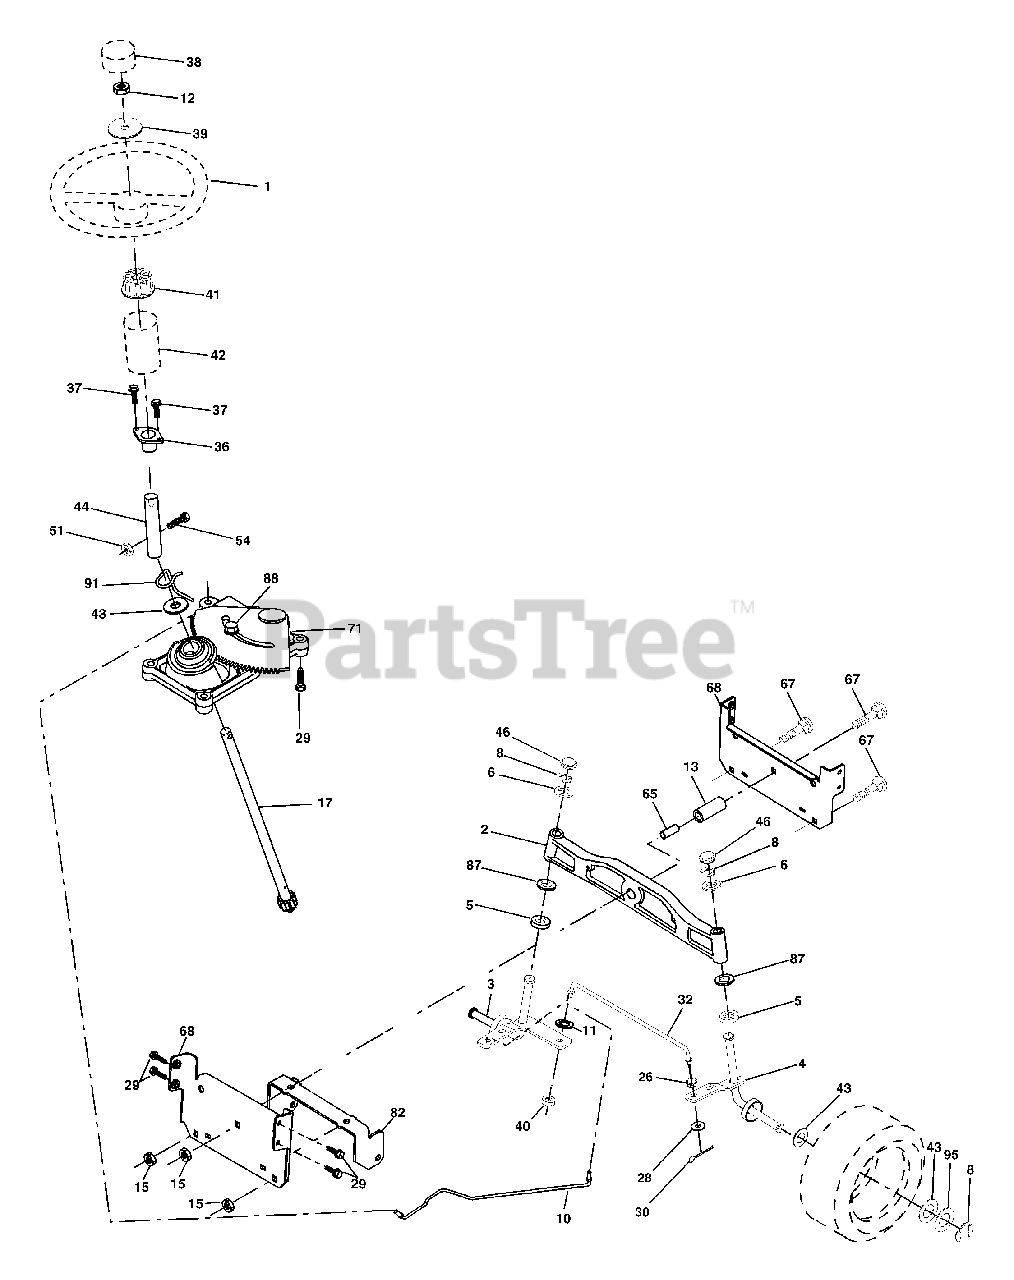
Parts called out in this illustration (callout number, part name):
1	Wheel Steering
2	Axle Asm
3	Spindle Asm LH
4	Spindle Asm RH
5	Bearing Race Thrust Harden
6	Washer 25/32 x 1-5/8 x 16 Ga.
8	Ring Klip #t5304-75
11	Washer Lock Hvy Hlcl Spr 3/8
12	Nut Hex Jam Toplock 1/2-20 unf
13	Spacer Brg Axle Front
15	Nut Hex Flange Lock
17	Shaft Asm Strg
26	Bushing Link Drag Blk LR
28	Washer 13/32 x 7/8 X 16 Ga.
29	Screw 3/8-16x3/4
30	Pin Cotter 1/8 x 3/4 Cad
32	Rod Tie Wire Form 19 75 Mech
36	Bushing Strg
38	Cap Wheel Steering
39	Washer 9/16 x 1-1/2 11 Ga.
40	Nut Crownlock 3/8-24
41	Adaptor Wheel Strg
42	Boot Steering Shaft
43	Washer 25/32 x 1 1/4 X 16 Ga.
44	Extension Steering Shaft LR/LT
46	Cap Spindle Fr Top Blk
51	Nut Crownlock 1/4-28
54	Bolt Hex 1/4-28 unf x 1-1/4 Gr. 8
65	Spacer Brace Axle
67	Bolt Rdhd Sq 3/8-16 x 2-1/4
68	Axle, Brace
71	Steering Asm
82	Bracket Susp Chassis Front
87	Washer Flat .781 x 1 1/2 x .14
88	Bolt Shoulder 7/16-20
91	Clip Steering
95	Washer Harden .793 x 1.637 x .060
